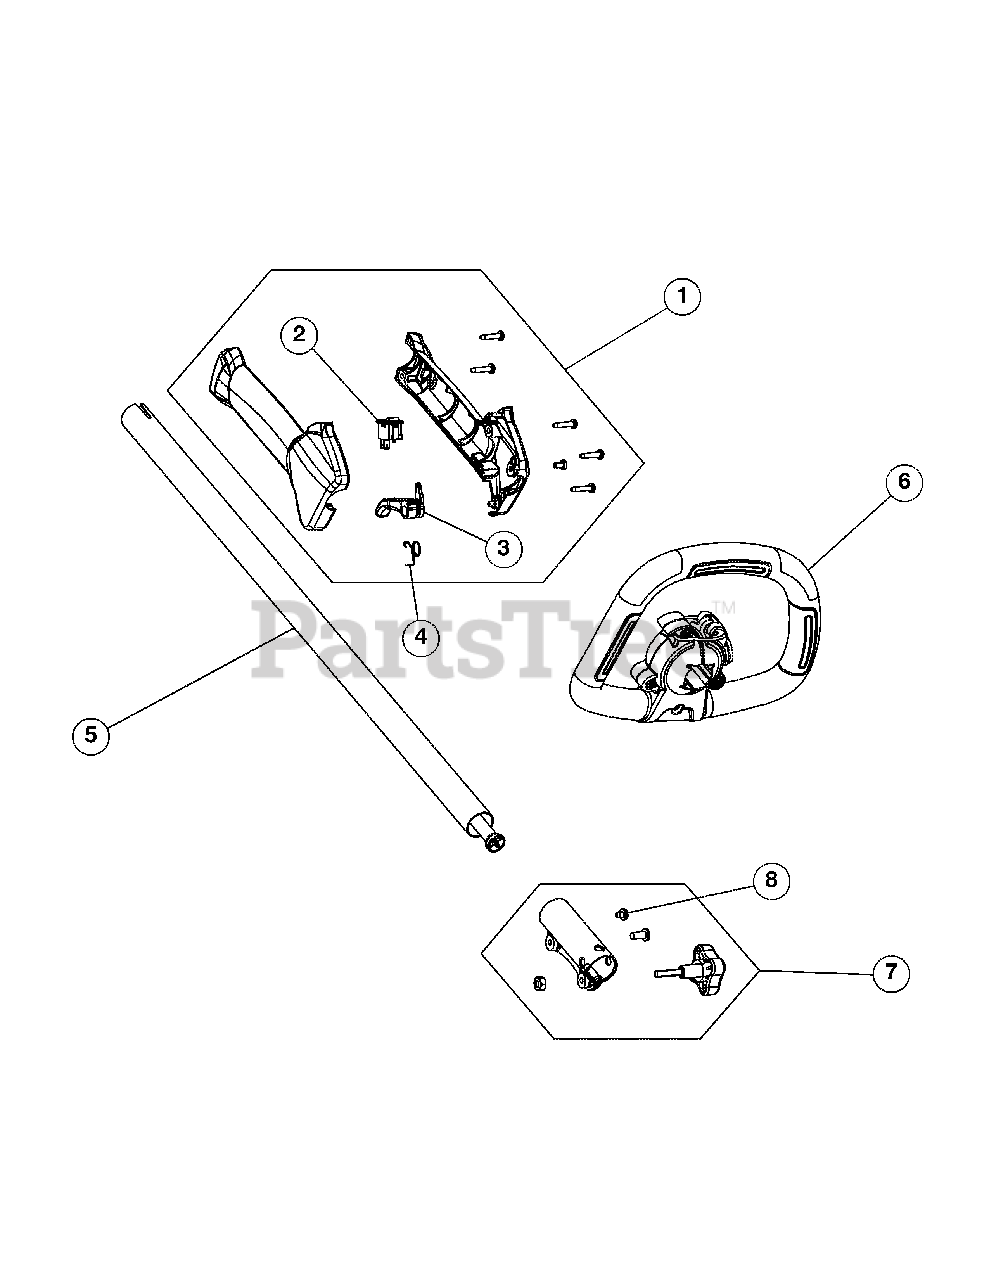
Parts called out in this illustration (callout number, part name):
1	Throttle Housing Assembly (Incl. 2-4)
3	Throttle Trigger
4	Throttle Trigger Spring
5	Upper Shaft Housing Assembly
6	Handle
7	Split Boom Coupler (Incl. 18)
